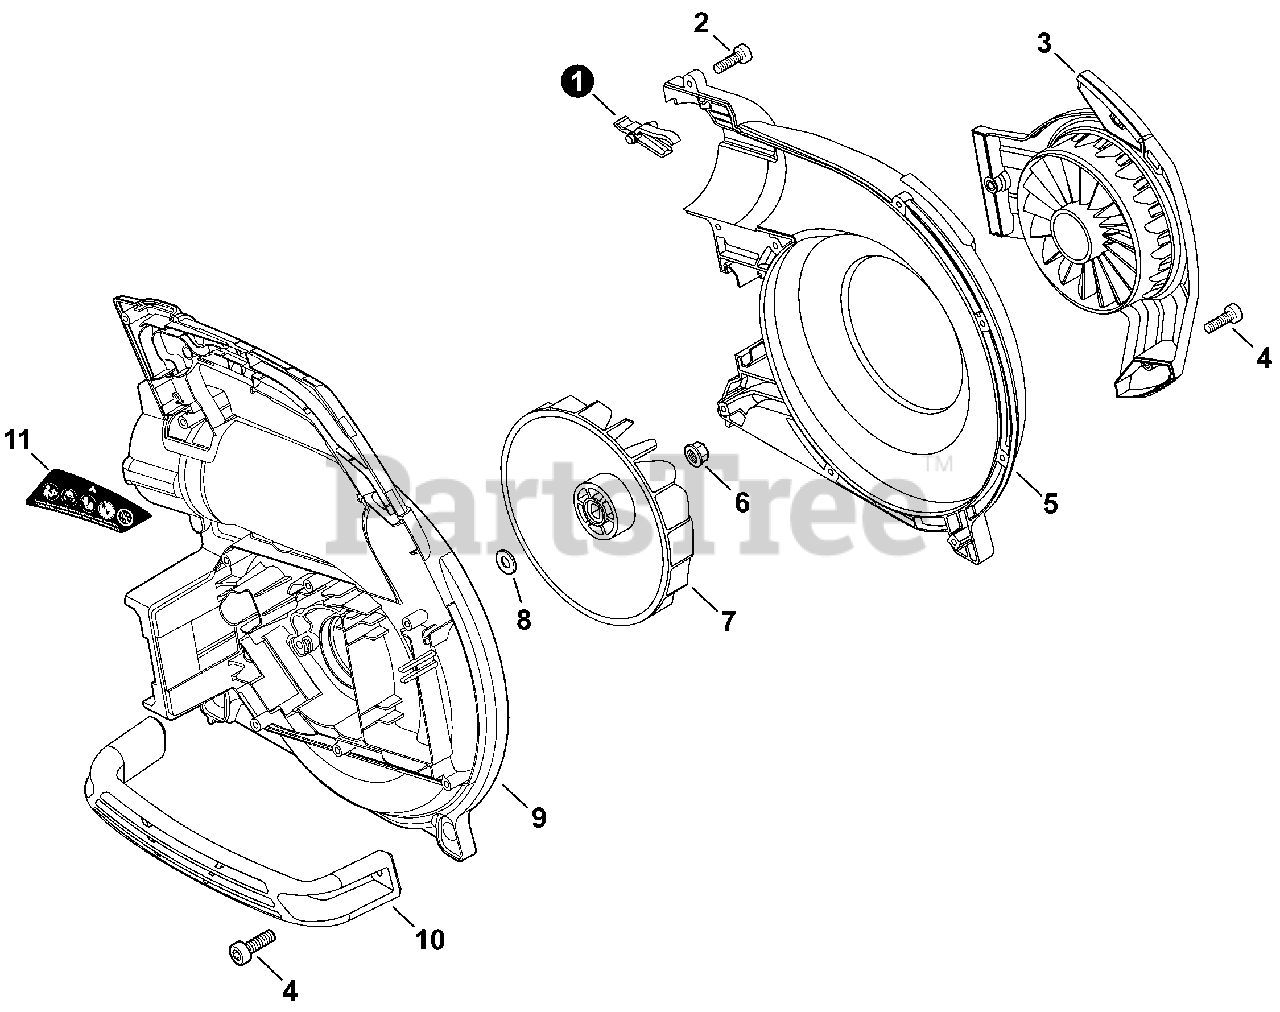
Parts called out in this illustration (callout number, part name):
1	LOCK, TUBE
2	BOLT, TORX 4×16
3	GUARD, DEBRIS
4	BOLT, TORX 5×20
5	COVER, FAN
6	NUT, FLANGE M8×1.25
7	FAN, BLOWER
8	WASHER 10.5×18×1.6
9	CASE, FAN
10	HANDLE, SUPPORT
11	LABEL, CAUTION
